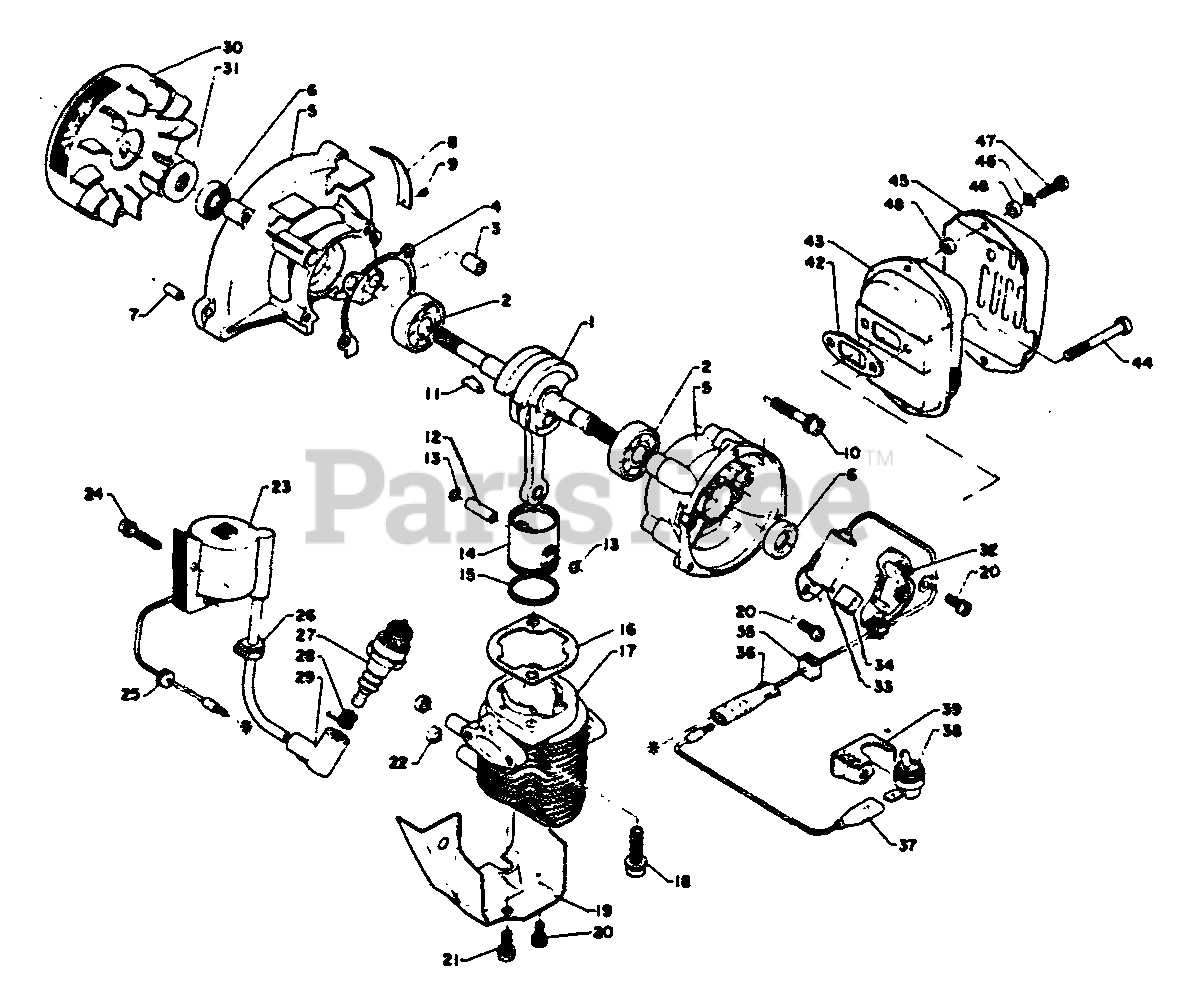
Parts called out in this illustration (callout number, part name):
1	CRANKSHAFT ASSY
2	BEARING, BALL - 6200
3	PIN - LOCATING
4	GASKET, CRANKCASE
5	CRANKCASE KIT
6	SEAL, OIL
7	PIN - LOCATING
8	PLATE, MODEL
9	RIVET
10	SCREW - 5X30
12	PIN, PISTON
13	RING, RETAINING
14	PISTON
15	RING, PISTON
16	GASKET, CYLINDER
17	CYLINDER
18	SCREW - 6X22
19	COVER, ENGINE
20	SCREW - 4X10
21	SCREW - 5X10
22	SPACER
23	COIL, IGNITION
24	SCREW - 4X22
25	GROMMET
27	SPARK PLUG -- BM-6A
28	TERMINAL, SPARK PLUG CAP
29	CAP, SPARK PLUG
30	FLYWHEEL
32	CONTACT POINT SET
33	CONDENSER
34	PAD, OIL
35	GROMMET
36	CORD, PRIMARY
37	LEAD - GROUND
38	SWITCH, IGNITION
39	BRACKET, SWITCH
42	GASKET, EXHAUST
43	MUFFLER
44	SCREW - 5X40
45	COVER, MUFFLER
46	WASHER - 4
47	SCREW - 4X14 -- TAPPING
48	SPACER
